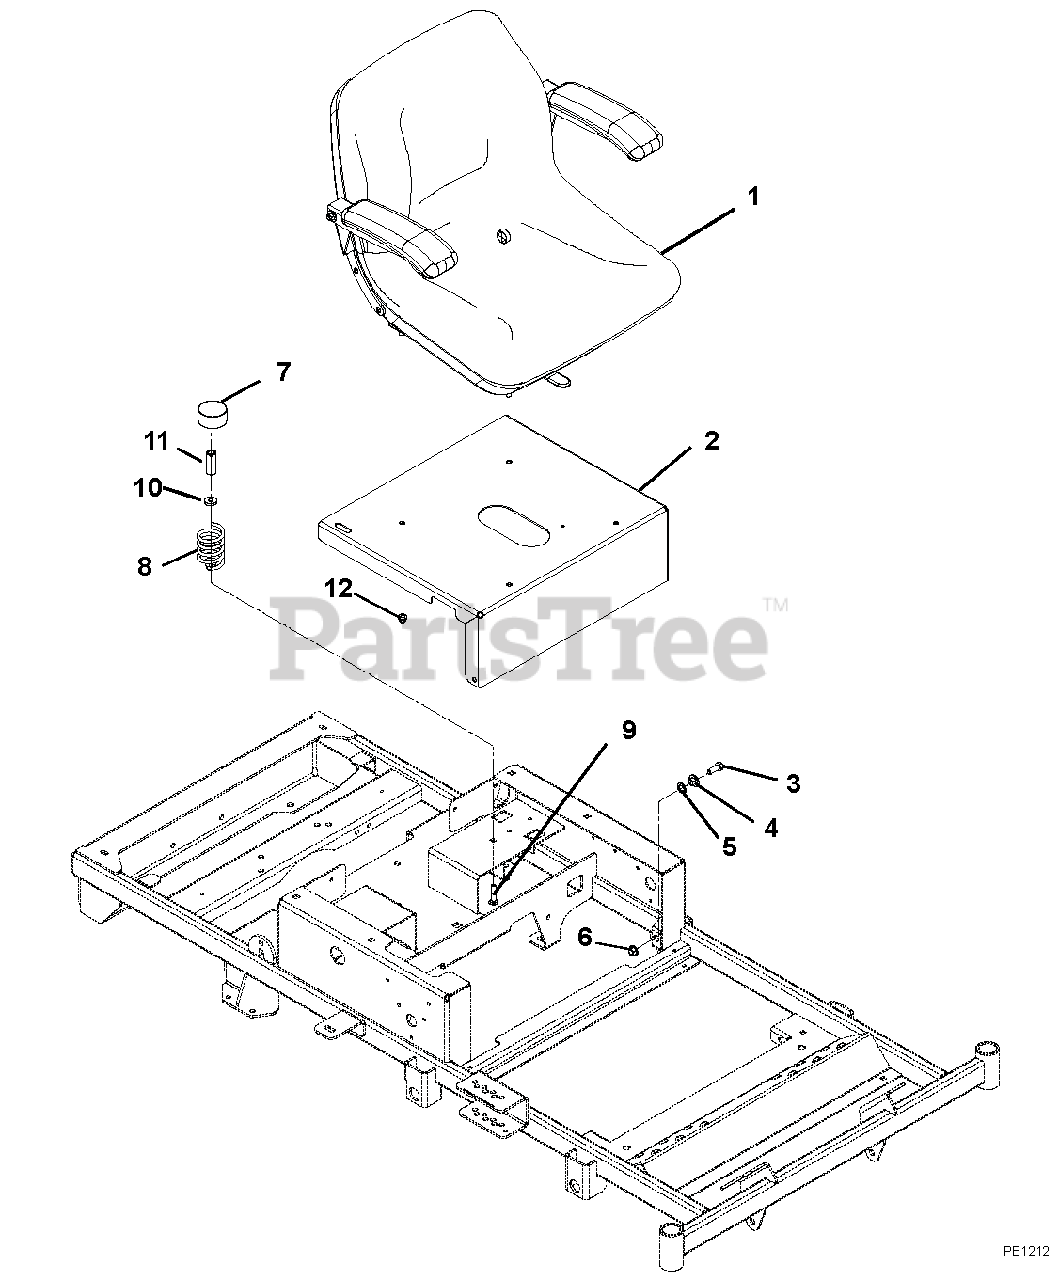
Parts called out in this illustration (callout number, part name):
1	SEAT, 1008 W/ARMREST SEATS INC
2	SEAT PLATE
3	@BLT-HEX .38-16X1.00 GR5 YWZC
4	BSHG-FLG .385X.500X.875X.406
5	WSHR-FL-STL .52X.827X.062 YWZC
6	@NUT-LK-NYL-FLG .38-16 YWZC
7	HUB CAP
8	SPRING, SEAT
9	@BLT-RDHDSQNK .31-18X1.50 G5YZ
10	WSHR-FL-STL .328X.87X.179 YWZC
11	NUT, COUPLING 5/16-18 X 1 3/4
12	@NUT-LK-NYL-FLG .31-18 YWZC
